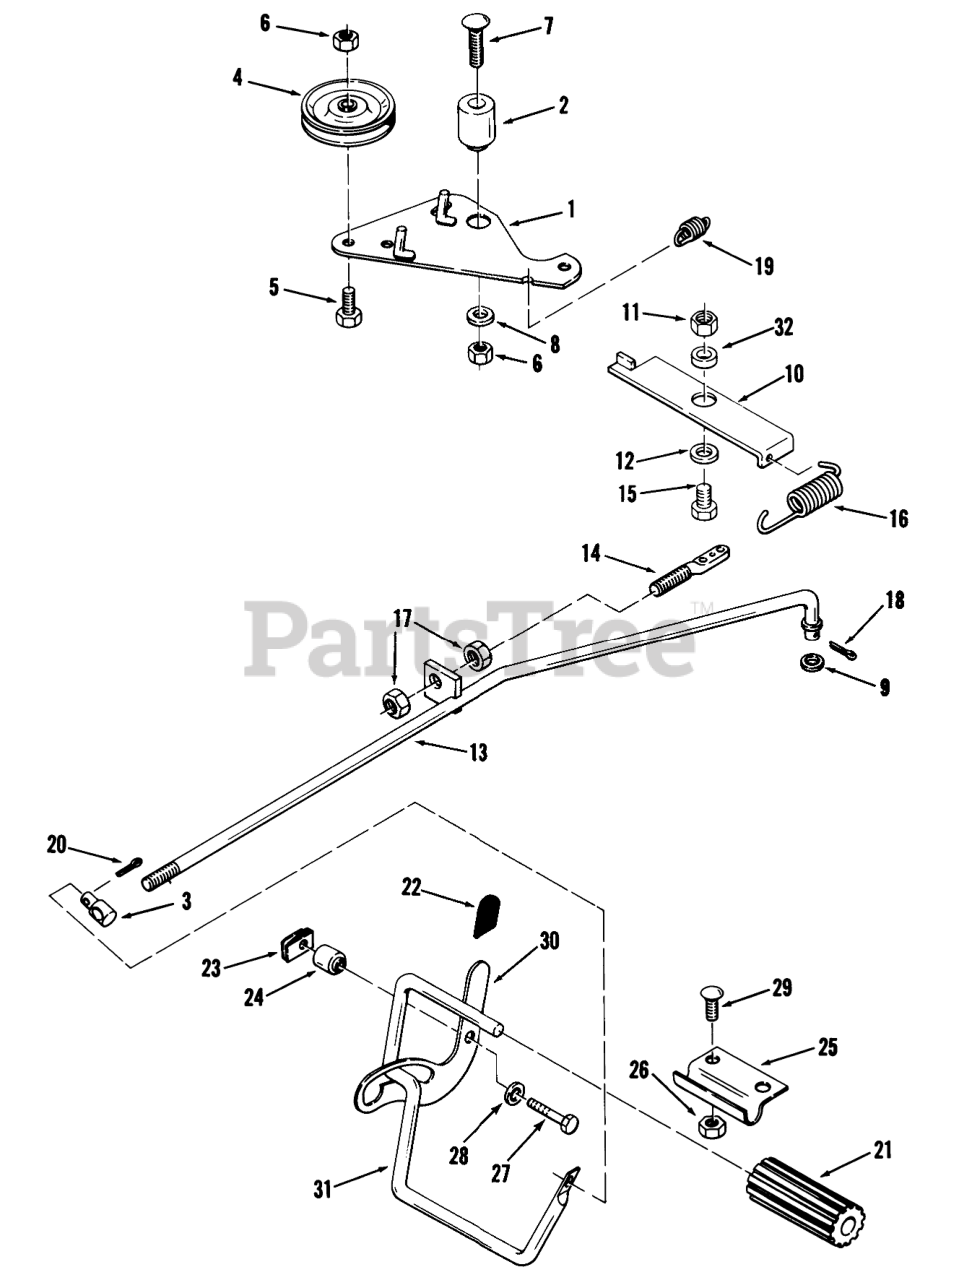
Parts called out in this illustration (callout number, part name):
3	TRUNNION
4	PULLEY-IDLER STATION
8	WASHER
12	WASHER 5/16 SAE
19	SPRING
22	GRIP
25	SPINDAL SUPPORT *R
